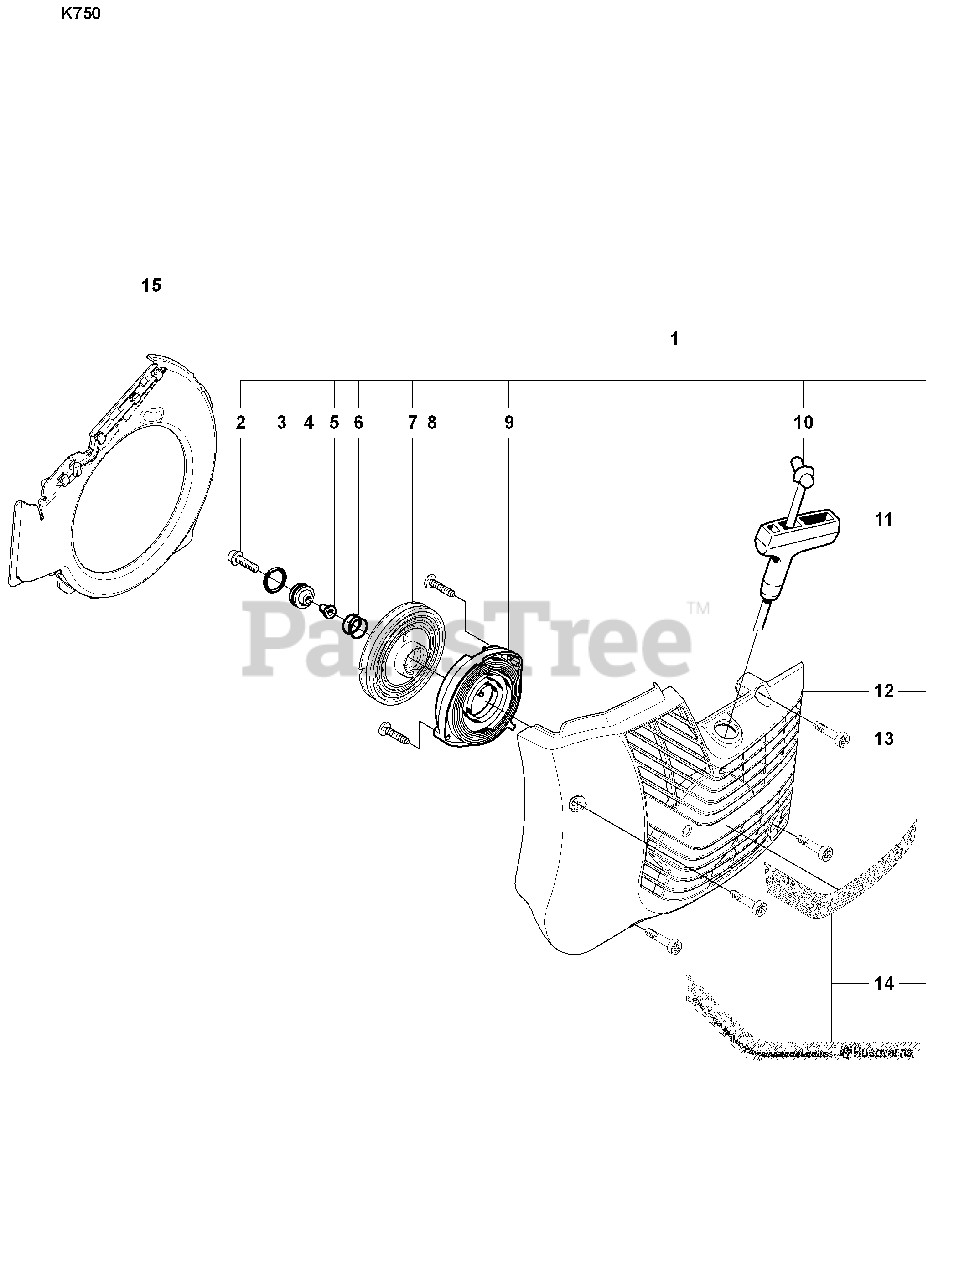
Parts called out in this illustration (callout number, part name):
1	STARTER
4	GROMMET
5	SPACING SLEEVE
6	COMPRESSION SPRING
7	STARTER PULLEY
9	RECOIL SPRING
10	STARTER CORD
11	STARTER HANDLE
12	STARTER COVER
14	LABEL
15	AIR CONDUCTOR
